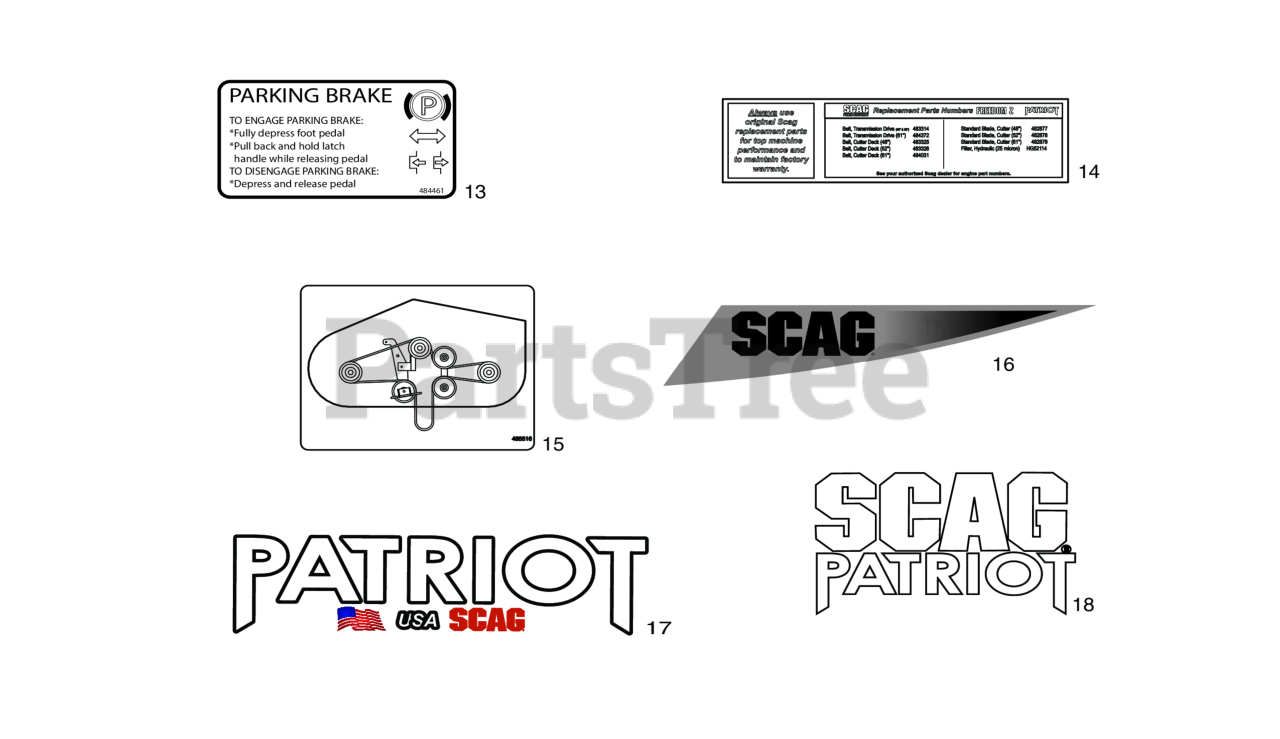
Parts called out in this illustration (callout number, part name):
13	Decal, Brake
14	Decal, SFZ / SPZ Replacement Parts
15	Decal, SZL / SFZ / SPZ Belt Routing
16	Decal, Scag - Fuel Tank
17	Decal, Patriot, (Scag Gold Logo) - Fuel Tank
18	Decal, Scag Patriot, (Scag Gold Logo) - Fuel Tank
